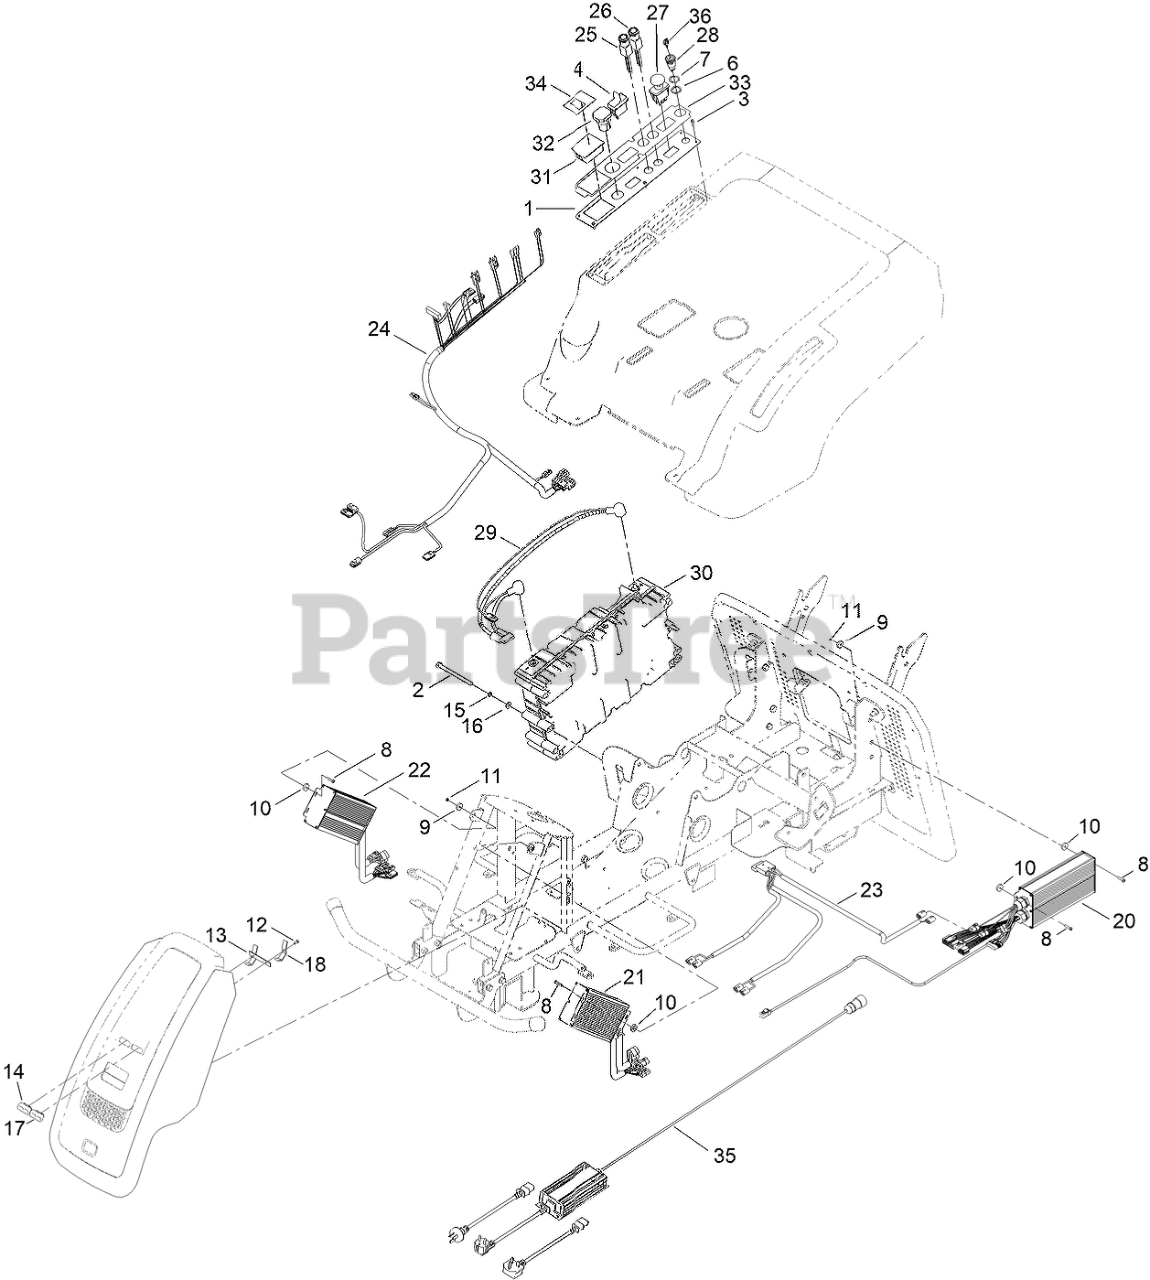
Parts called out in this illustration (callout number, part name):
1	PLATE, CONTROL CENTRE
2	BOLT, BATTERY
4	SWITCH, DIRECTIONAL
6	WASHER
7	WASHER, WAVE
9	FLAT BUSH, RUBBER
10	BUSH, RUBBER
13	PLATE, LIGHTS
14	CASING, LIGHT (RIGHT, FRONT)
15	WASHER-SPRING
16	WASHER-PLAIN
17	CASING, LIGHT (LEFT, FRONT)
18	BRACKET, LED LIGHTS
20	CONTROLLER, DRIVE MOTOR
21	CONTROLLER, CUTTER MOTOR (LH)
22	CONTROLLER, CUTTER MOTOR (RH)
23	WIRING HARNESS (POWER)
24	WIRING HARNESS (CONTROL PANEL)
25	RMO, BUTTON
26	CCT, BUTTON
27	CUTTER BUTTON ASM
28	SWITCH, IGNITION
29	WIRE, BATTERY
30	BATTERY, DIRECT COLLECT
31	DISPLAY, CONTROL PANEL
32	PORT, USB
33	DECAL - CONTROL PANEL
34	DECAL - HOUR METER
35	CHARGER, 2.5A E-RIDER
36	KEY, E-RIDER
